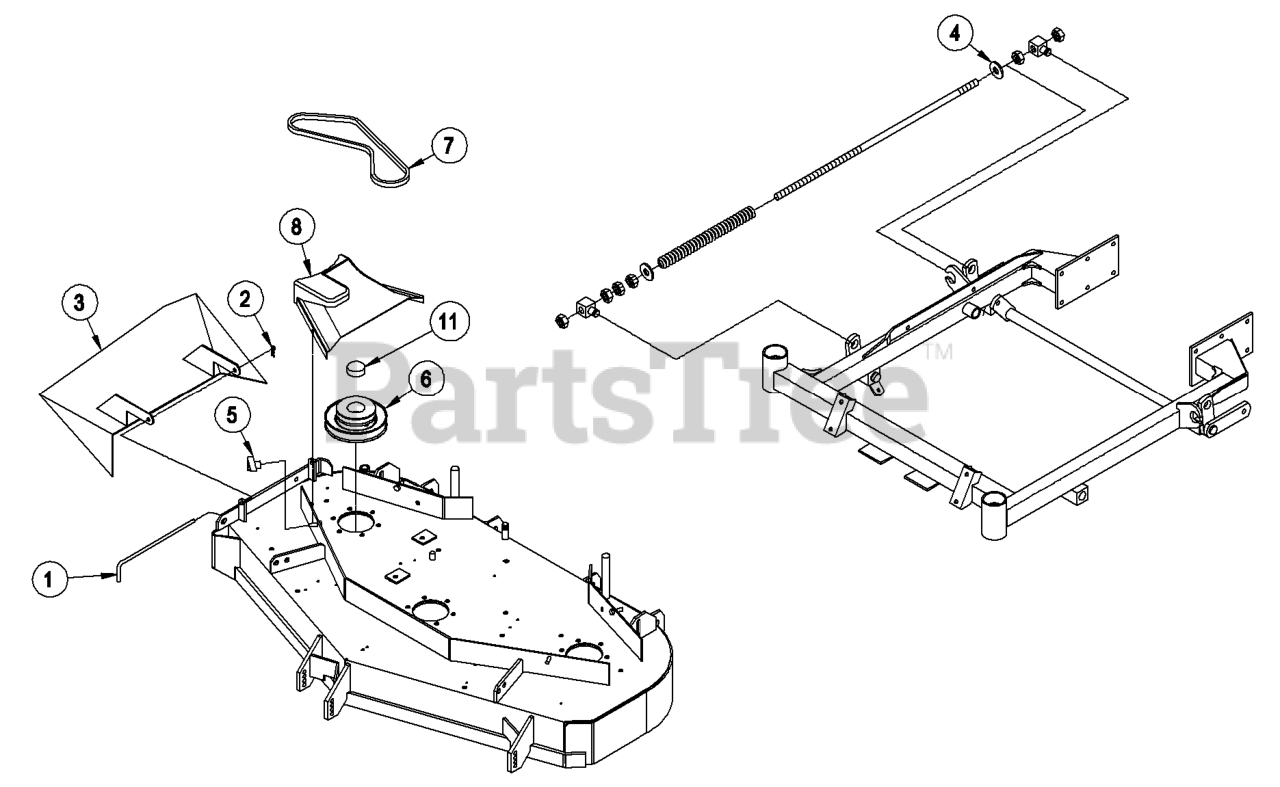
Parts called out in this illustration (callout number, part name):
1	PIN, CHUTE PIVOT PLTD
2	PIN-COTTER
5	KNOB-3 PRONG
6	SHEAVE, BLOWER DR 48"
7	BELT-BLOWER
8	COVER, BELT 44/48
10	SCREW-HH
11	PLUG, BLACK NYLON 1.75
